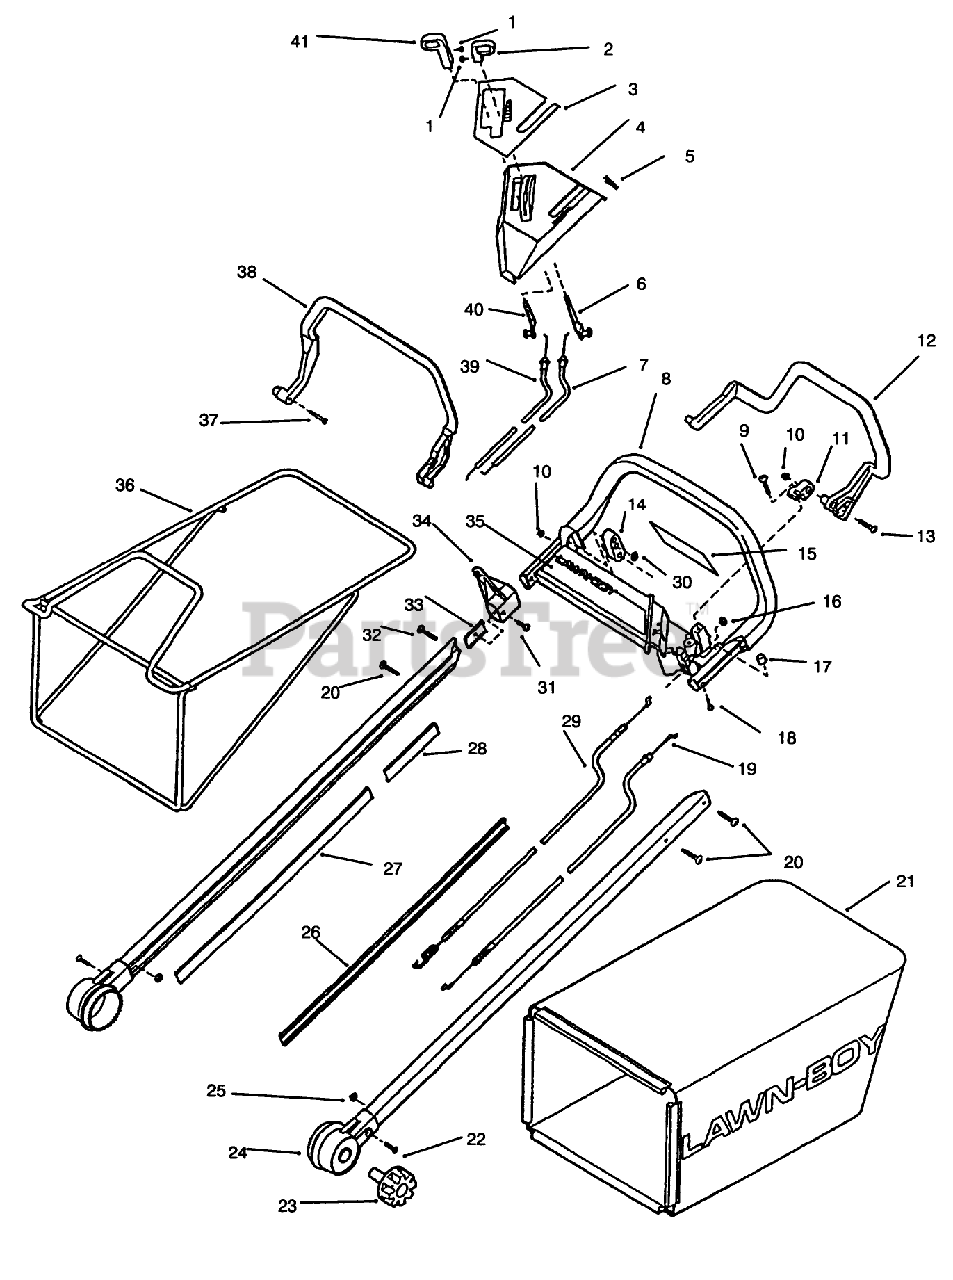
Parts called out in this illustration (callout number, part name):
4	COVER-CNTRL UPPER
10	LOCKNUT FLAN
11	PIVOT BAIL PL
12	BAIL-S.P. *
14	BLOCK BAIL PL
19	CABLE ASSEMBLY
21	REPL BAG FOR 684190
23	KNOB-HDLE MT.ASM*B
24	HANDLE SHAFT AY
25	LOCKNUT FLAN
26	INSERT - HANDLE
29	CABLE AY
30	NUT-LOCK, NI
32	SCREW-TRUSS
39	CABLE AY. WESCON
41	KNOB & SCREW AY
